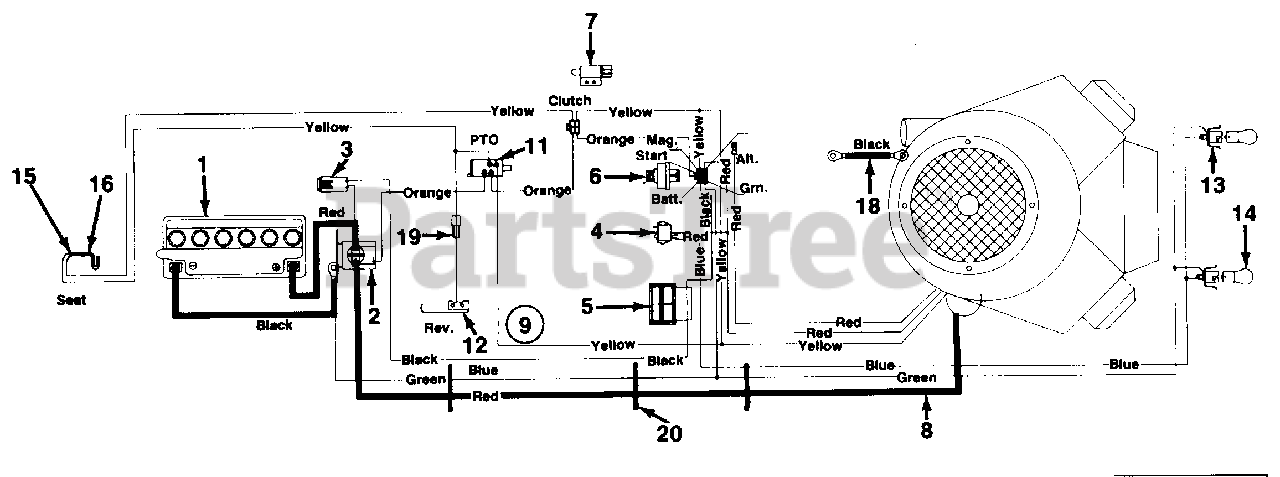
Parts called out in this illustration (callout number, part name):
1	Battery-12V
2	Solenoid
3	Fuse 20 Amps
4	Light Switch
5	Ammeter
6	Ignition Switch
7	Safety Switch
8	Electric Wire-30.0" Lg.
9	Wire Harness
11	Safety Switch
12	Safety Switch
13	Headlight Socket
14	Headlight Bulb
15	Safety Switch
16	Safety Switch
18	Ground Wire-7.5" Lg.
19	Extension Wire
